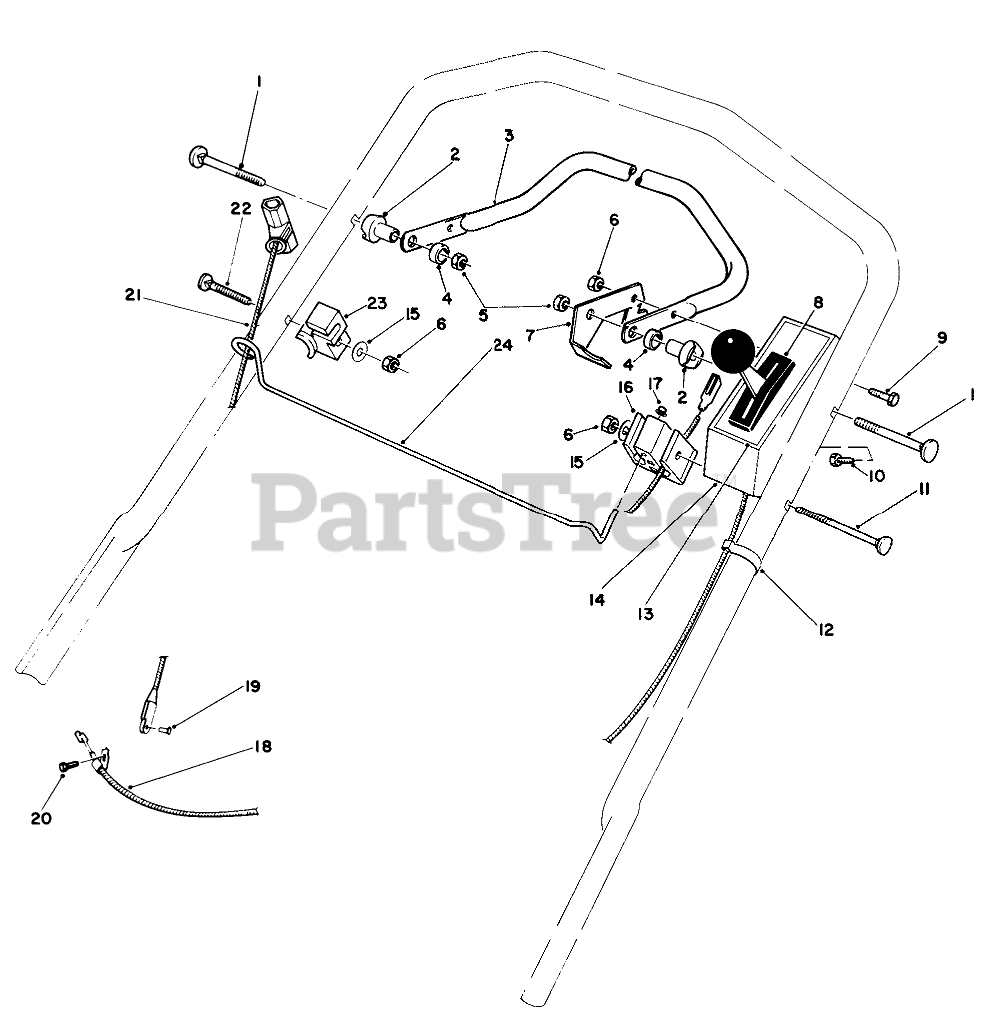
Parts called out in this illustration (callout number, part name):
1	5/16-18 X 2 HNDLE SCREW
2	SPACER-SUPPORT
3	Bar-Control
4	SPACER-NYLON
5	NUT-LOCK, NI
6	NUT-LOCK, NI
7	Lever-Control
8	SERVICE THROTTLE CONTRO
9	SCREW-HH
10	SCREW-HWHTF
11	HANDLE SCREW
12	BOWDEN CLIP
13	Decal-Control Cover
14	Panel-Control (Incl. Ref. #13)
15	WASHER-FLAT
16	SUPPORT-CABLE
17	NUT-SPEED
18	BRAKE CABLE
20	SCREW-HH
21	Rope-Starter
22	SCREW-HANDLE
23	ROD CATCH
24	ROPE ROD PLATED
